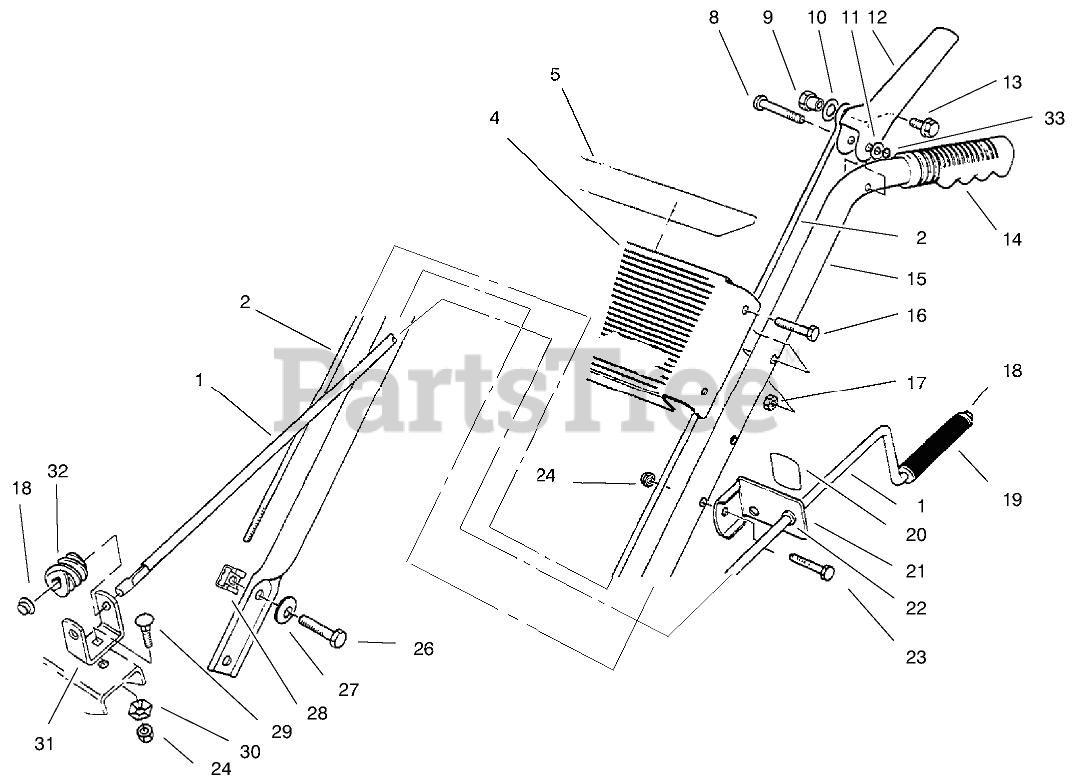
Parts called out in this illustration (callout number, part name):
1	ROD-CONTROL, CHUTE
2	LINK-UPPER
4	Panel-Escutcheon
5	DECAL-ESCUTHEON BACK
8	PIN-LEVER, CONTROL
9	POST-MOUNTING, LINKAGE
10	WASHER-PLAIN
11	WASHER-FLAT
12	HANDLE-CONTROL
13	SCREW-HHF
14	GRIP-HANDLE
15	HANDLE-LEFT
16	SCREW-HH
17	NUT-LOCK, NI
18	RETAINER-PUSH ON
19	GRIP-CONTROL, CHUTE
20	DECAL-CHUTE DIRECTION
21	Bracket-Chute Control (Incl. Ref.# 20 & 22)
22	Bushing
23	SCREW-HH
24	NUT-LOCK, NI
26	SCREW-HH
27	WASHER-BELLEVILLE
29	SCREW-CARR
30	WASHER-LOCK
31	BRACKET-WORM
32	GEAR-WORM, CHUTE
33	RING-CLIP
